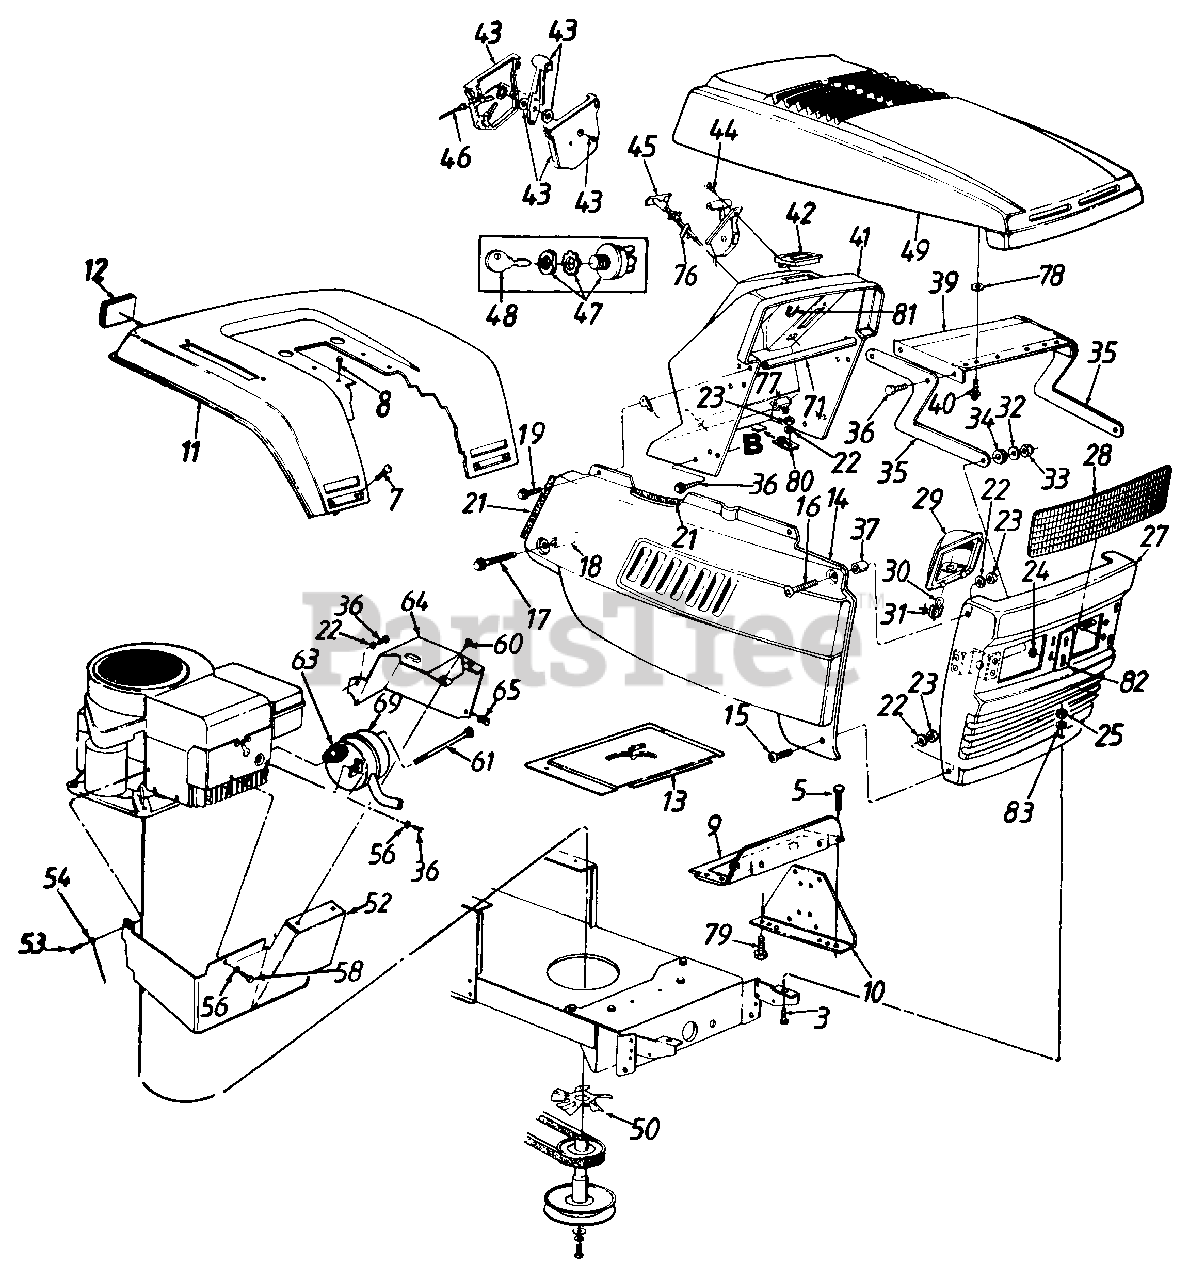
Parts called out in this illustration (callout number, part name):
3	Hex Bolt 5/16-18 x .75" Lg.
5	Hex Wash. Hd. Scr. 5/16" x .5" Lg.
7	Carriage Bolt 1/4-20 x .5" Lg.
8	Hex Wash. Hd. Tap Scr. 5/16 x .75" Lg.
16	Truss Mach. Scr. 1/4-20 x 1.0" Lg.
17	Hex Wash. TT-Tap Scr. 1/4-20 x 1.75" Lg.
18	Spacer .26" I.D. x 1.32"
19	Hex Rolling Tap Scr. 1/4-20 x .75" Lg.
21	Trim Strip - 18" Lg.
22	L-Wash. 1/4" I.D.
23	Hex Nut 1/4-20 Thd.
24	Speed Nut 5/16" Thd.
25	Hex Nut 5/16-18 Thd.
29	Headlamp Housing
30	Headlamp
31	Twist Lock Lamp Socket
32	Bell-Wash .345" I.O. x .88"
33	Hex L-Nut 5/16-18 Thd.
34	Rubber Washer
37	Spacer .262" I.D. x .31"
41	Dash
42	Ammeter
43	Throttle Control Box Ass'y.
44	Mach. Scr. #10 x .44" Lg.
45	Choke Control 23" Lg.
46	Throttle Control Wire 18.5" Lg.
47	Ignition Switch
48	Ignition Key
49	Hood - Red
52	Muffler Heat Shield - Front
53	Truss Mach. Scr. 5/16-18 x .75" Lg.
54	Ground Wire
56	Spr. Wash. 1/4" 1.0.
58	Hex Bolt 1/4-20 x 3/8" Lg.
60	Hex B-Tap Scr. 010 x .38" Lg.
61	Shoulder Bolt
63	Exhaust Gasket
64	Muffler Heat Shield - L.H.
65	Speed Nut #10-24 Thd.
69	Muffler
71	Grille Support Tube
76	Choke Retainer
77	Light Switch
78	Fl-Wash .406" I.D. x .812" O.D.
79	Hex Bolt 1/4-20 x .62" Lg.
80	Dash Fastening Tab
81	Cable Tie
82	Chrome Label
